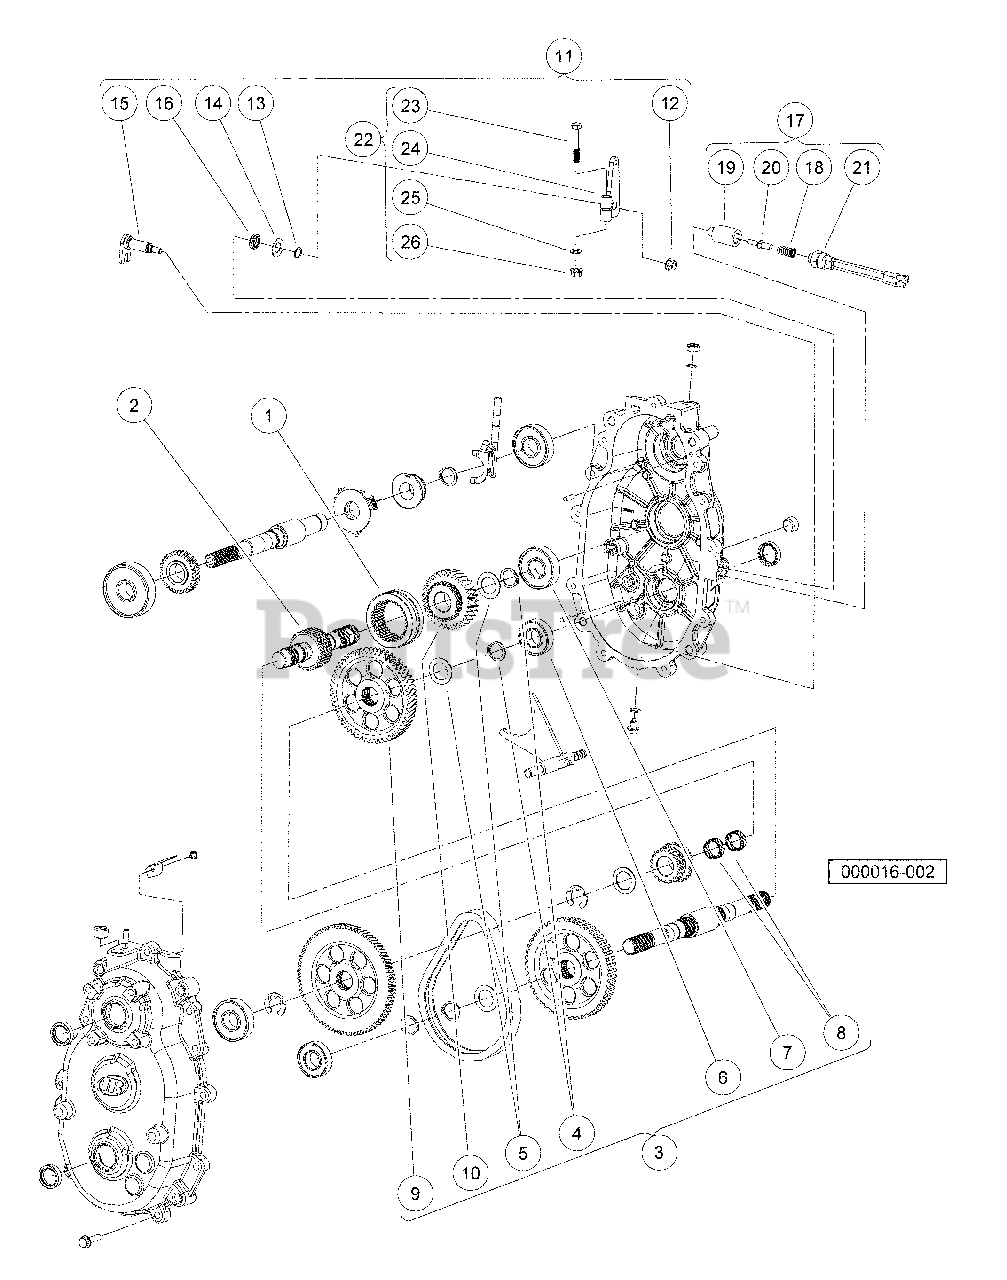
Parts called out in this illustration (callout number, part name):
1	Dog, Engagement
2	Shaft, Intermediate
3	Kit, Forward Gear Repair
4	Ring, Retaining, Basic External
5	Washer, Thrust, 1.007 X .062
6	Bearing, Ball
7	Bearing, Ball
8	Bearing, Needle
11	Kit, Trans Shift Shaft Repair
12	Nut, Lock Hex, Nylon, 5/16-24
13	Ring, Retaining, External 9/16
14	Washer, Flat, .58 X 1.08 X .05
15	Weldment, Shift, Shaft
17	Kit, Neutral Switch Repair
19	Guide, Detent Bullet
20	Bullet, Detent
21	Switch, Indicator, Pollak
22	Kit, Bellcrank, D Shape, Clamp
23	Bolt, 3/8-16 X 2.00 Hex Head
24	Asm, Bellcrank, D Shape, Clamp
25	Washer, 3/8 Type A Flat
26	Locknut, 3/8-16 Hex
